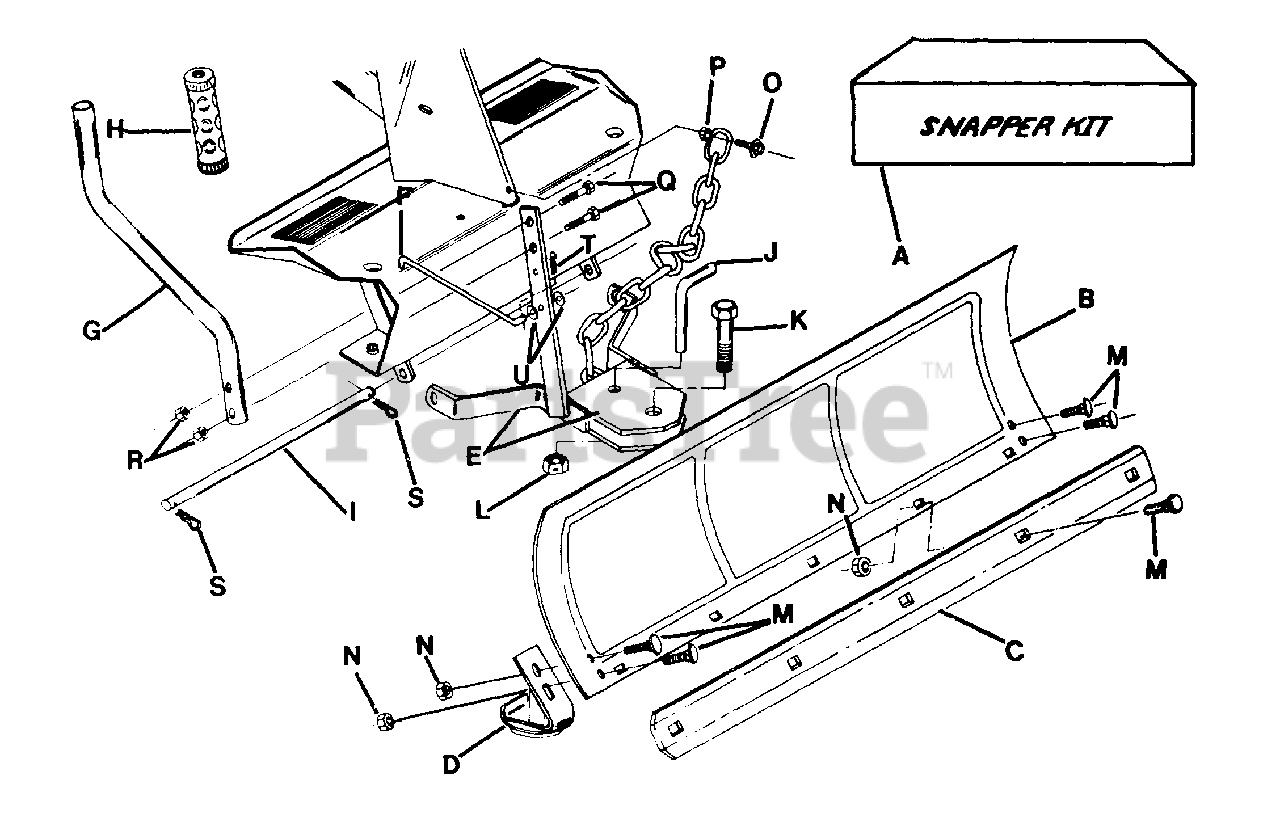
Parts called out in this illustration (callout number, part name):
A	KIT, RIDER SNOW PLOW
B	BLADE, SNOW
C	SCRAPPER
D	SLIDE, BLADE
E	BRACKET, BLADE LIFT (STRUCTURE)
G	HANDLE
H	GRIP, HANDLE
I	PIN, HOLDING
J	PIN, 'L'
K	SCREW, HEX HEAD CAP 1/2-20x2-3/4
L	NUT, 1/2-20 HEX LOCK
M	BOLT, CARRIAGE 3/8-16x3/4
N	NUT, 3/8-16 HEX LOCK
O	SCREW, SELF-TAPPING 5/16-18x1
P	NUT,, 5/16-18 HEX
Q	SCREW, HEX HEAD CAP 3/8-24x1-3/4
R	NUT, 3/8-24 HEX LOCK
S	PIN, HAIR
T	COTTER-PIN 1/8 x 3/4
U	WASHER, 5/16 SAE
